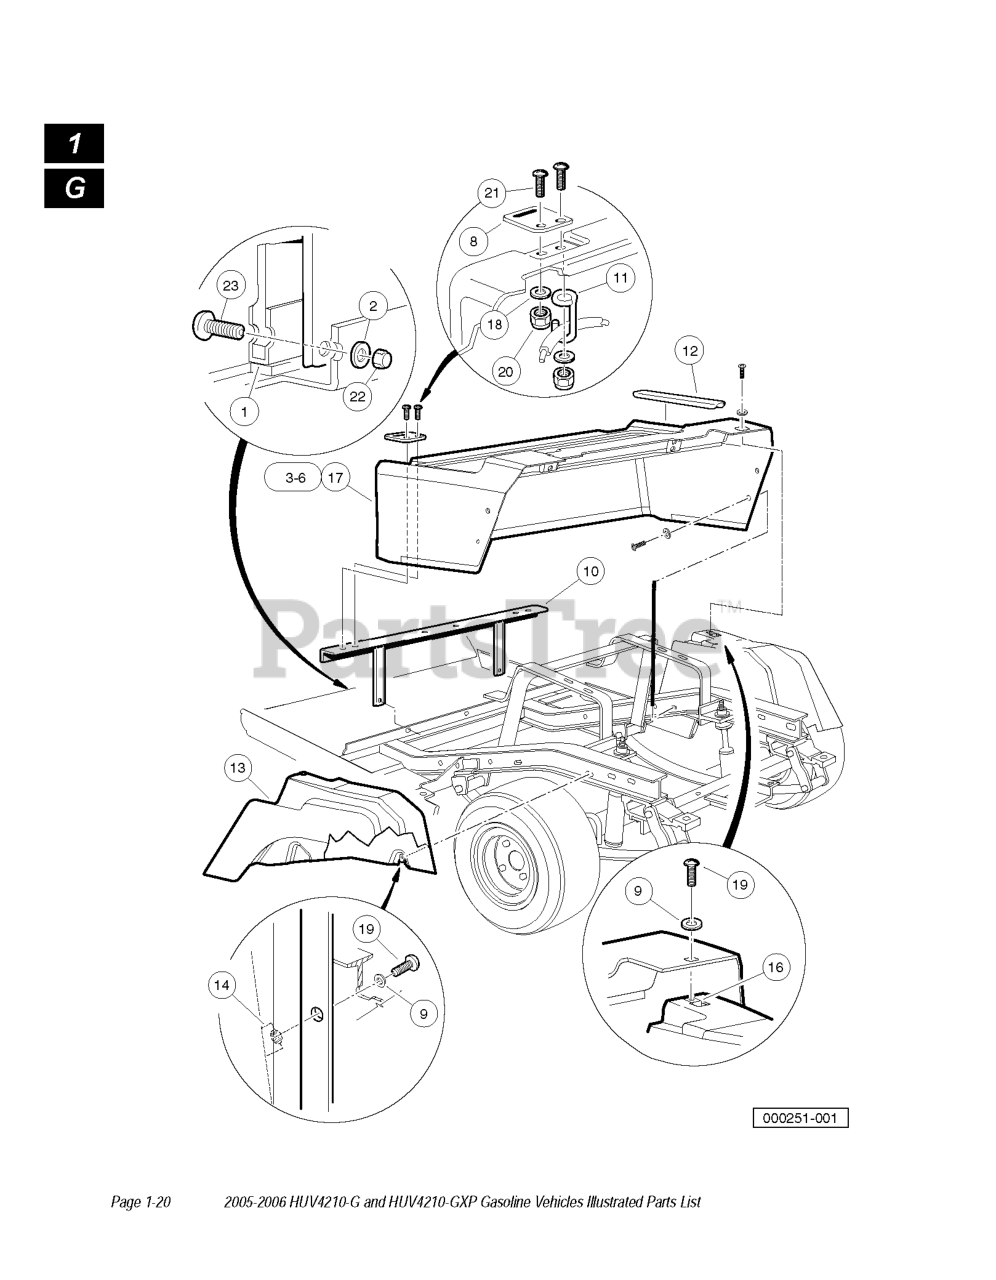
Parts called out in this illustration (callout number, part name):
1	BODY KICK PLATE
8	BODY, HINGE PLATE
10	BODY SUPPORT FRONT
11	CABLE RETAINER
13	FENDER ASM, BODY, DVR
14	U-NUT, 1/4-20 PALNUT BRAND
15	FENDER ASM, BODY, PASS
16	U-NUT, 1/4-20 PALNUT BRAND
17	BODY, REAR, GAS, CUT, ORG
18	WASHER 1/4 FLAT
19	SCREW, 1/4-20 X .75 HEX
20	LOCKNUT, 1/4-20 NYLON INSERT
21	SCREW, 1/4-20 X 1.0 TRS HD MCH
22	LOCKNUT, 1/4-20 NYLON INSERT
23	SCREW, 1/4-20 X 1.0 TRS HD MCH
